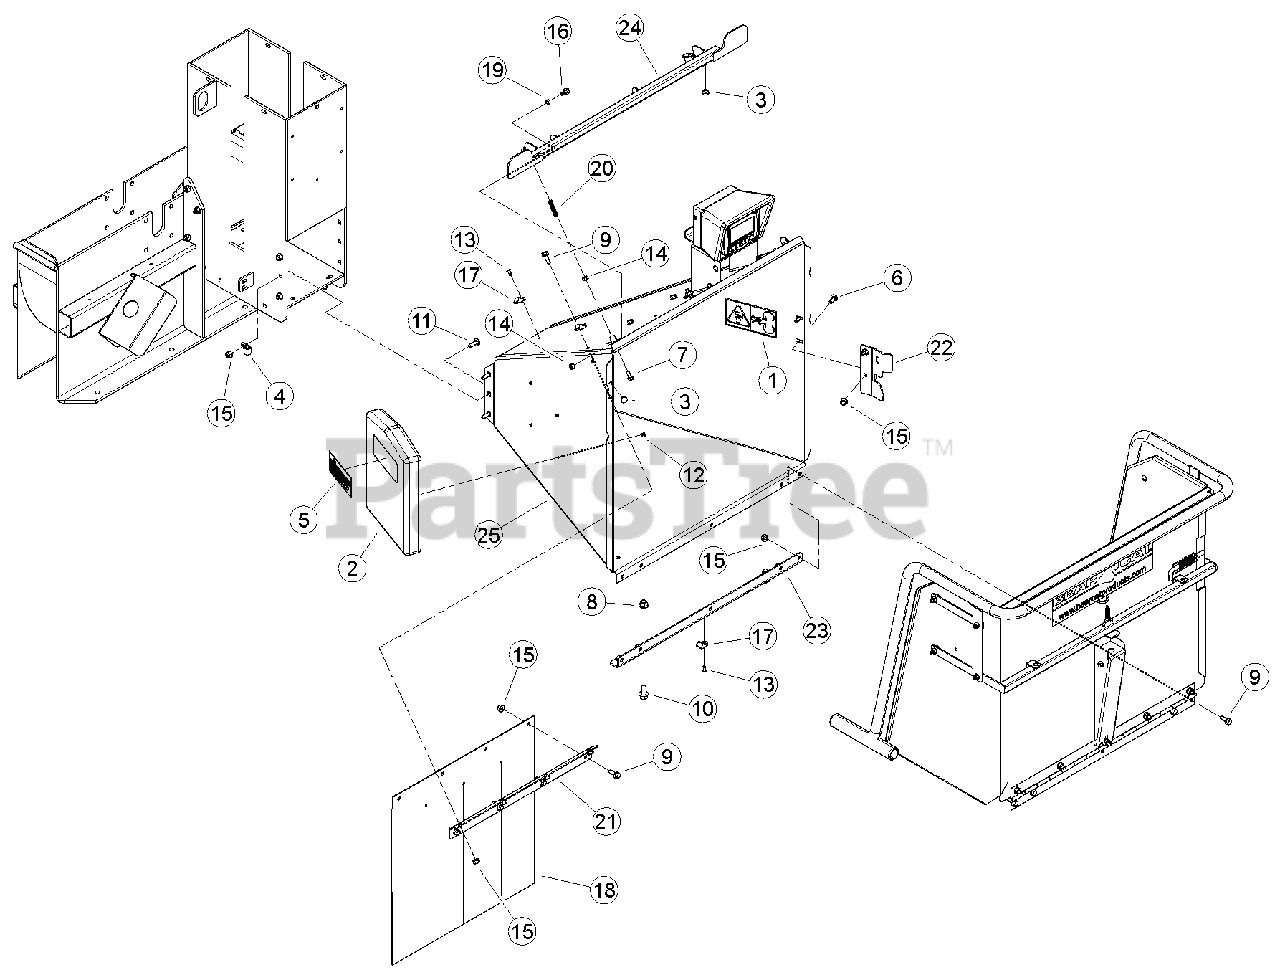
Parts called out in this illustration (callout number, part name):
1	DECAL, BLADE DANGER ISO
2	CONTAINER, INSTR. MANUAL
3	BUMPER, RUBBER
4	CLAMP, 9/16 COATED
5	DECAL, MUTILINGUAL MANUAL
6	BOLT, 3/8 X 1" GR5 CRG NC ZP
7	BOLT, 5/16 X 3/4 FLANGE NC
8	NUT, 1/2-13 NYLOCK FLANGE
9	BOLT, 3/8 X 1 FLANGE NC
10	BOLT, 1/2-13 1.00 GR5 FLANGE NC
11	BOLT, 3/8 X 1-1/4"GR5 CRG NC ZP
12	RIVET, AL BLIND 1/4 X 1/2 DOME HEAD
13	RIVET, AL BLIND 1/4 X 3/4 DOME HEAD
14	NUT, 5/16-18 NYLOCK-FLANGE
15	NUT, 3/8-16 NYLOCK FLANGE
16	BOLT, 5/16-18 X 3/4 ZP FLANGE SHOULDER
17	CLAMP, CABLE MOUNT
18	FLAP, 9 INCH CHUTE
19	BEARING, .375 X .50 X .25 LONG
20	SPRING, COMPRESSION .437 DIA X 2.0 LONG
21	SUPPORT, 9 INCH CHIPPER FLAP
22	PLATE, TRAY LATCH
23	ANGLE, INFEED SUPPORT
24	WELDMENT, 8/9" TOP SAFETY BAR
25	WELDMENT, BIG CHIPPER CHUTE
